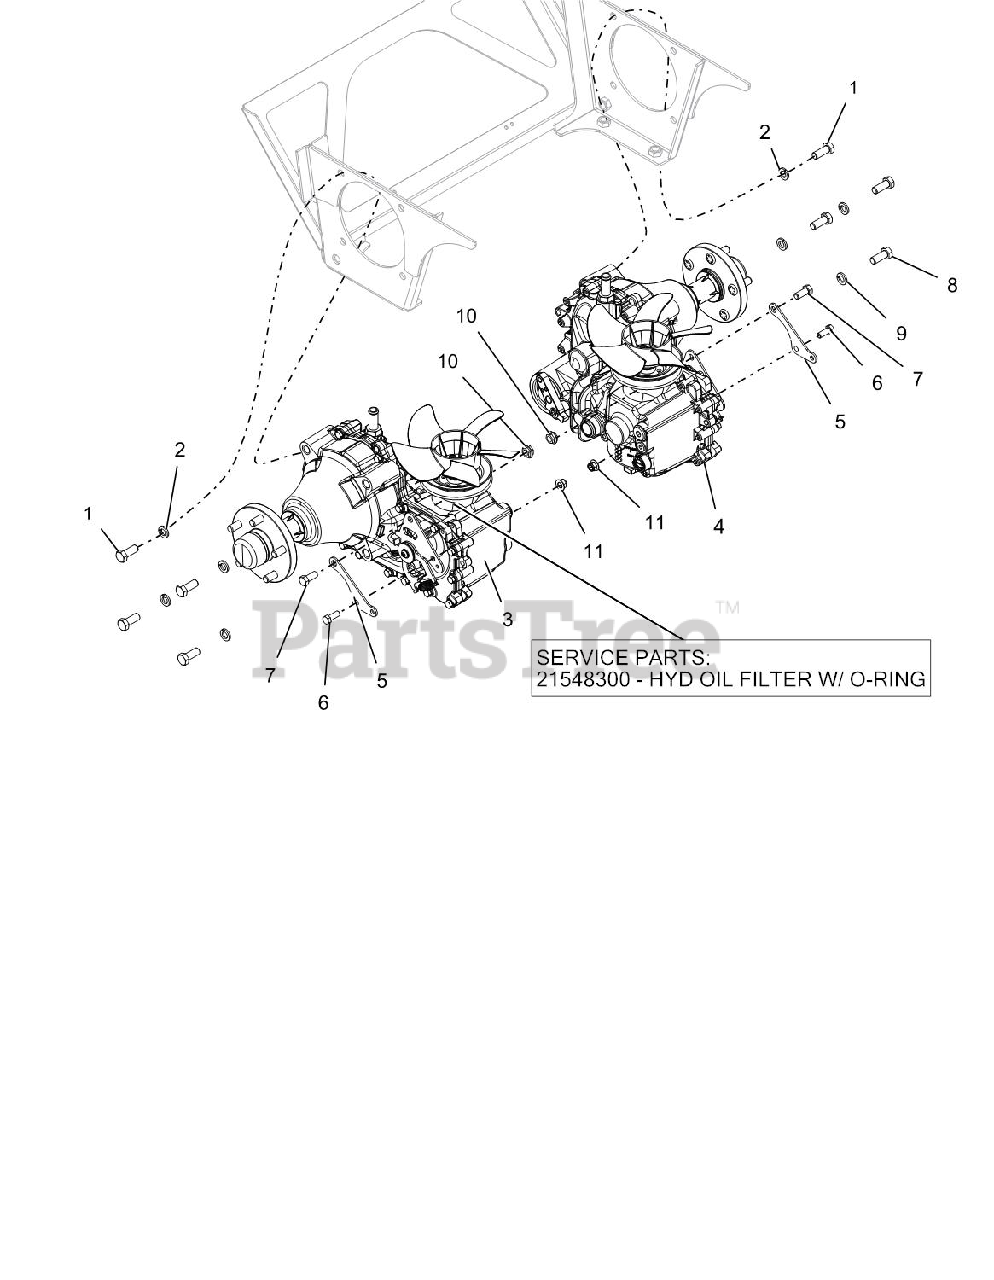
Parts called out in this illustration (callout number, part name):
1	BLT-HEX .50-13X1.25 GR5 YWZC
2	WSHR-LK .50X.125 REG YWZC
3	TRANS, R.H. HG ZT-5400
3	HYDRO OIL FILTER W/ O-RING
4	TRANS, LH HG ZT-5400
5	BRKT, DRIVE CONTROL LINKAGE MTG - BLK
6	BLT-HEX .38-16X1.00 GR5 YWZC
7	BLT-HEX .44-14X1.00 GR5 YWZC
8	BLT-HEX .50-13X1.25 GR5 YWZC
9	WSHR-LK .50X.125 REG YWZC
10	NUT-LK-NYL-FLG .44-14 YWZC
11	NUT-LK-NYL-FLG .38-16 YWZC
